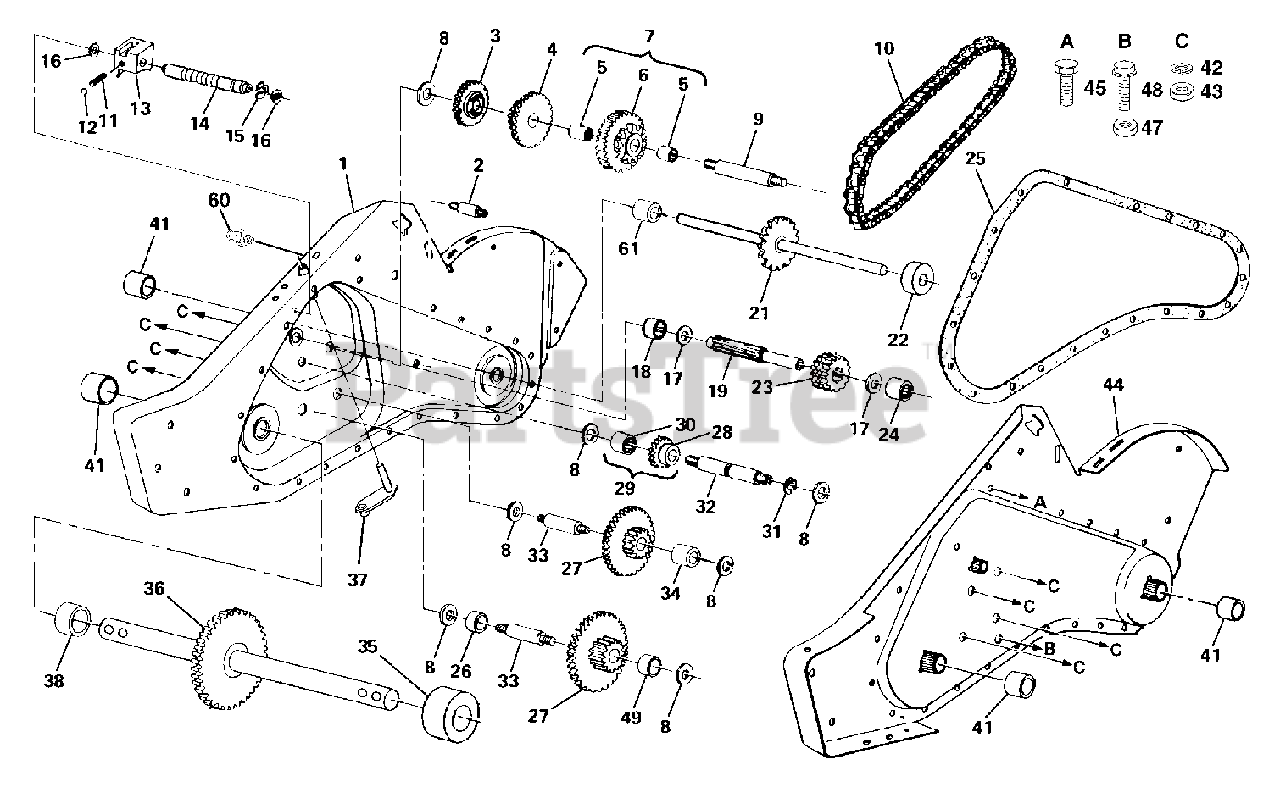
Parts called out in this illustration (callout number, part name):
1	GEARCASE ASM.RH.W/BEARING 2002
2	SPACER.GEARCASE
3	GEAR.REVERSE.8HP
5	BEARING.NEEDLE.CRT
6	SPROCKET ASMBLY, TINE
7	SPROCKET ASMBLY W/BEARINGS
9	SHAFT.REDUCTION.TILLER
10	CHAIN.ROLLER.TILLER
11	SPRING-SHIFT CRT
12	STEEL BALL KIT
13	SHIFT FORK TI
14	SHAFT.SHIFT.1.00 PINION
16	WASHER, SEAL (2 2)
17	THRUST WASHER
18	BEARING TI
19	SHAFT INPUT
21	SHAFT.ASM.TINE.21
22	SPACER 1.008X1-3/4X.645
23	GEAR.PINION
24	NEEDLE BRNG LT
25	GASKET.GEARCASE.8HP
27	GEAR, CLUSTER CRT
28	REVERSE GEAR
29	GEAR ASMBLY, REVERSE IDLER
30	NEEDLE BEARING TI
32	SHAFT, REVERSE IDLER
33	SHAFT, REDUCTION
34	SPACER.765 X 1.12 X .380.
35	SPACER, GROUND DRIVE RH
36	SHAFT ASSY CRT
37	BRACKET ASM.SHIFT.CRT
38	SPACER, GROUND DRIVE
41	SEAL ASM, OIL
42	LOCKWASHER
43	NUT.ASF.HEX.7/16
44	GEARCASE ASM.LH.W/BEARING 2002
45	BOLT.5/16HEX.WHS.HD
48	SCREW 5/16-18X4
60	FITTING.GREASE.TAPERED
61	SPACER.1.015 X 1.50 X .765
